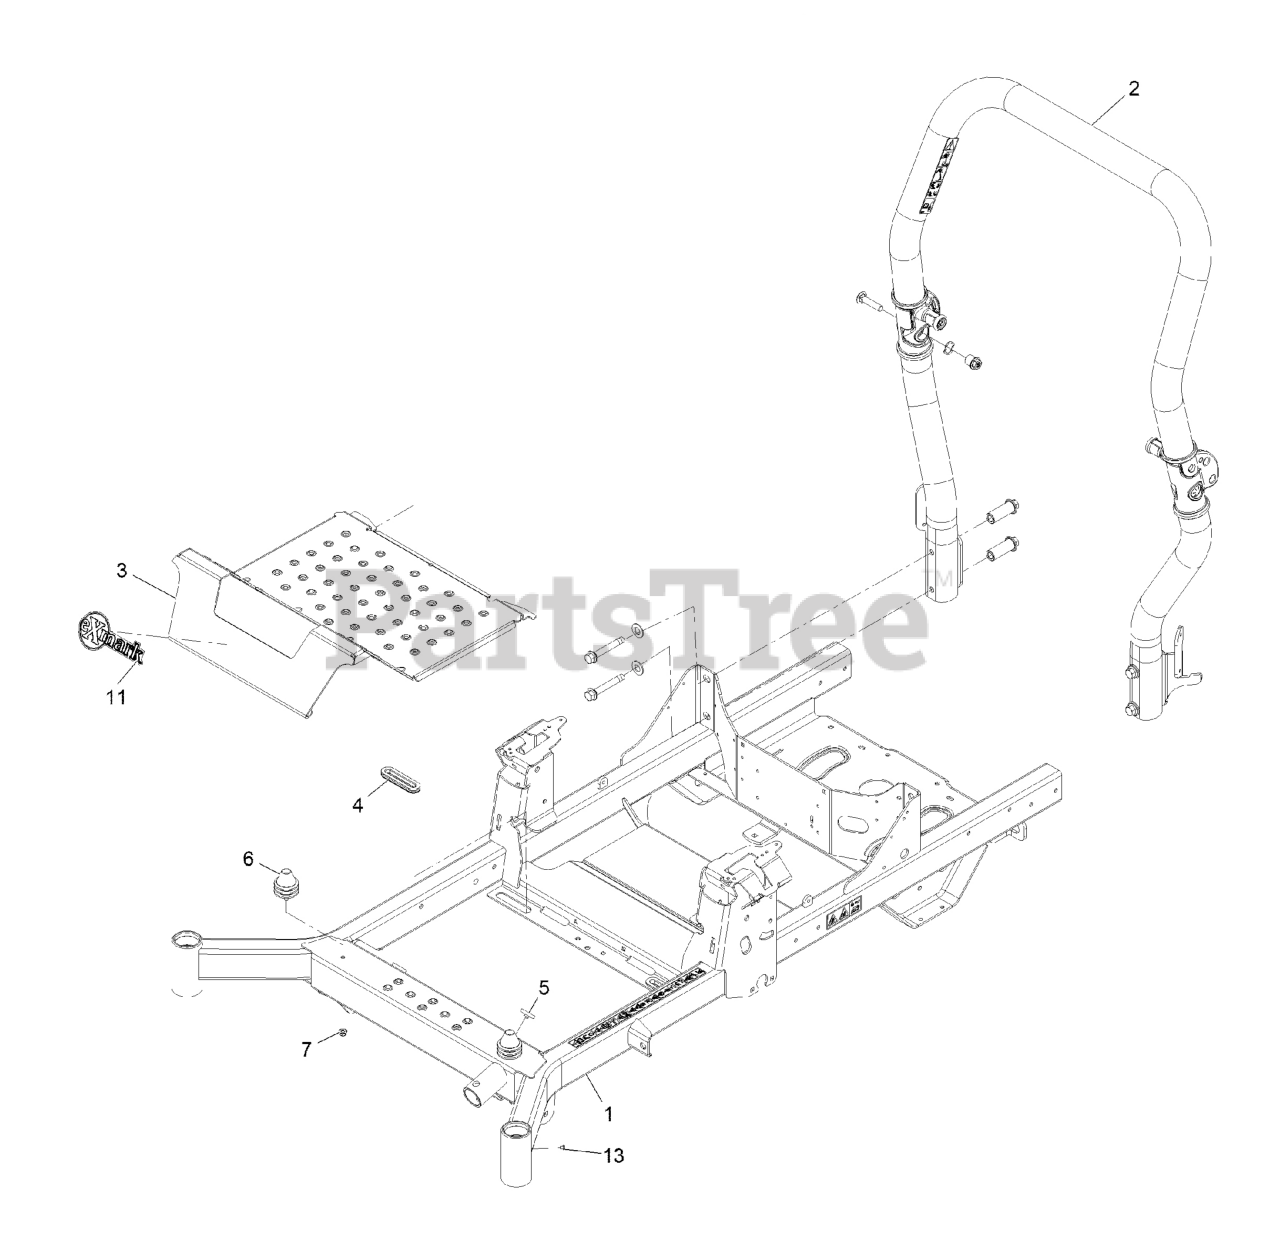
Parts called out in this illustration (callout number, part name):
1	ASM, Frame W/ Decal
2	ASM, ROPS
3	Pan-Floor
4	GROMMET-RUBBER
5	BUMPER-PUSH-IN, RUBBER
6	ISOLATOR
7	NUT-HF, NI
11	DECAL-EXMARK LOGO
